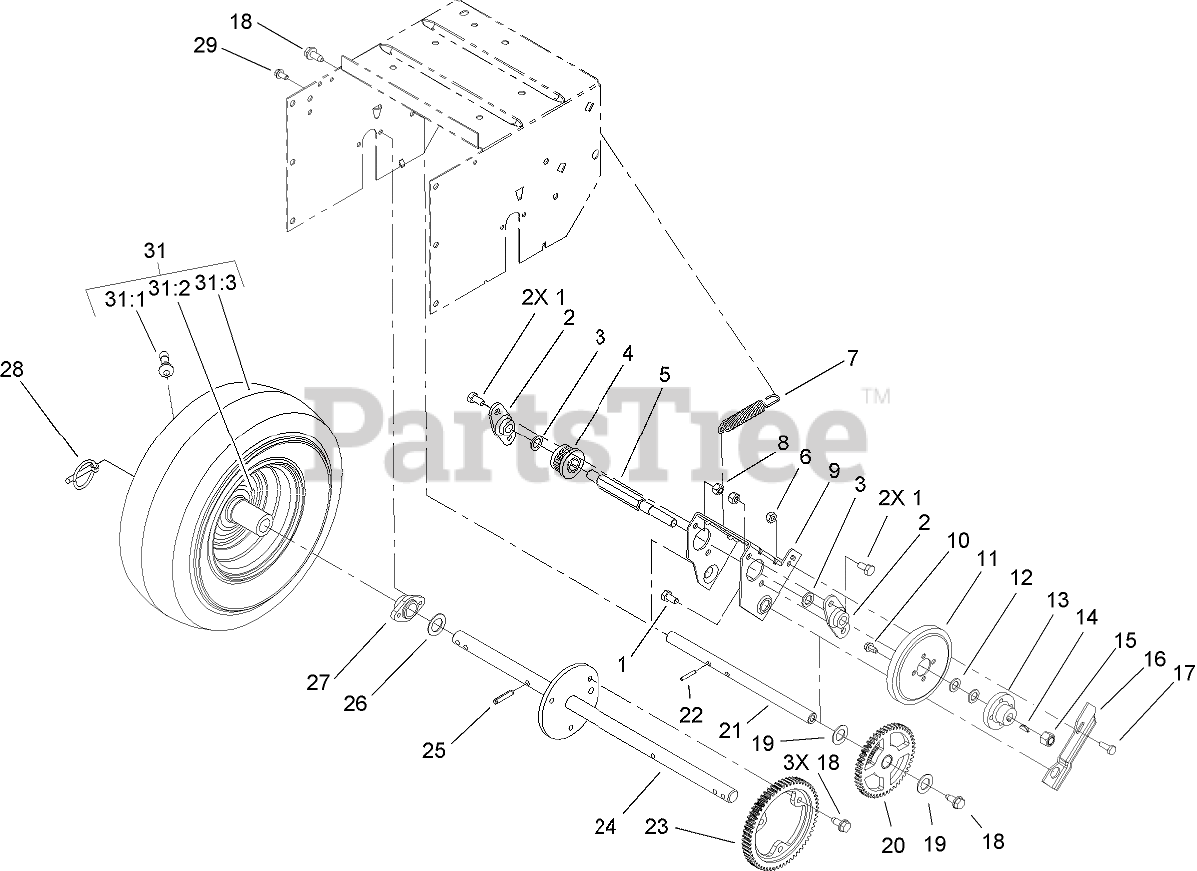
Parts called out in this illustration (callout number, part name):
1	SCREW-HH
2	BEARING-WHEEL, FRICTION
3	WASHER-FLAT
4	PINION
5	SHAFT-WHEEL, FRICTION
6	NUT-LOCK, NI
7	SPRING-TRACTION
8	NUT-LOCK, NI
9	BRACKET-SLIDING
10	SCREW-HWH
11	WHEEL-FRICTION
12	WASHER-THRUST
13	HUB-WHEEL, FRICTION
14	KEY-WOODRUFF
15	NUT-LOCK, NI
16	CAM-RECEIVER
17	SCREW-HH
18	SCREW-HWHTF
19	WASHER-SPECIAL
20	INTERNAL GEAR AND BUSHING ASM
21	SHAFT-PIVOT
22	PIN-SPRING
23	GEAR-AXLE
24	SHAFT-AXLE
25	PIN-ROLL, SLOTTED
26	WASHER-THRUST
27	BEARING-AXLE
28	PIN-LYNCH
29	SCREW-HWH
30	LH WHEEL AND TIRE ASM
31	RH WHEEL AND TIRE ASM
31:1	STEM-VALVE
31:2	RIM-WHEEL
